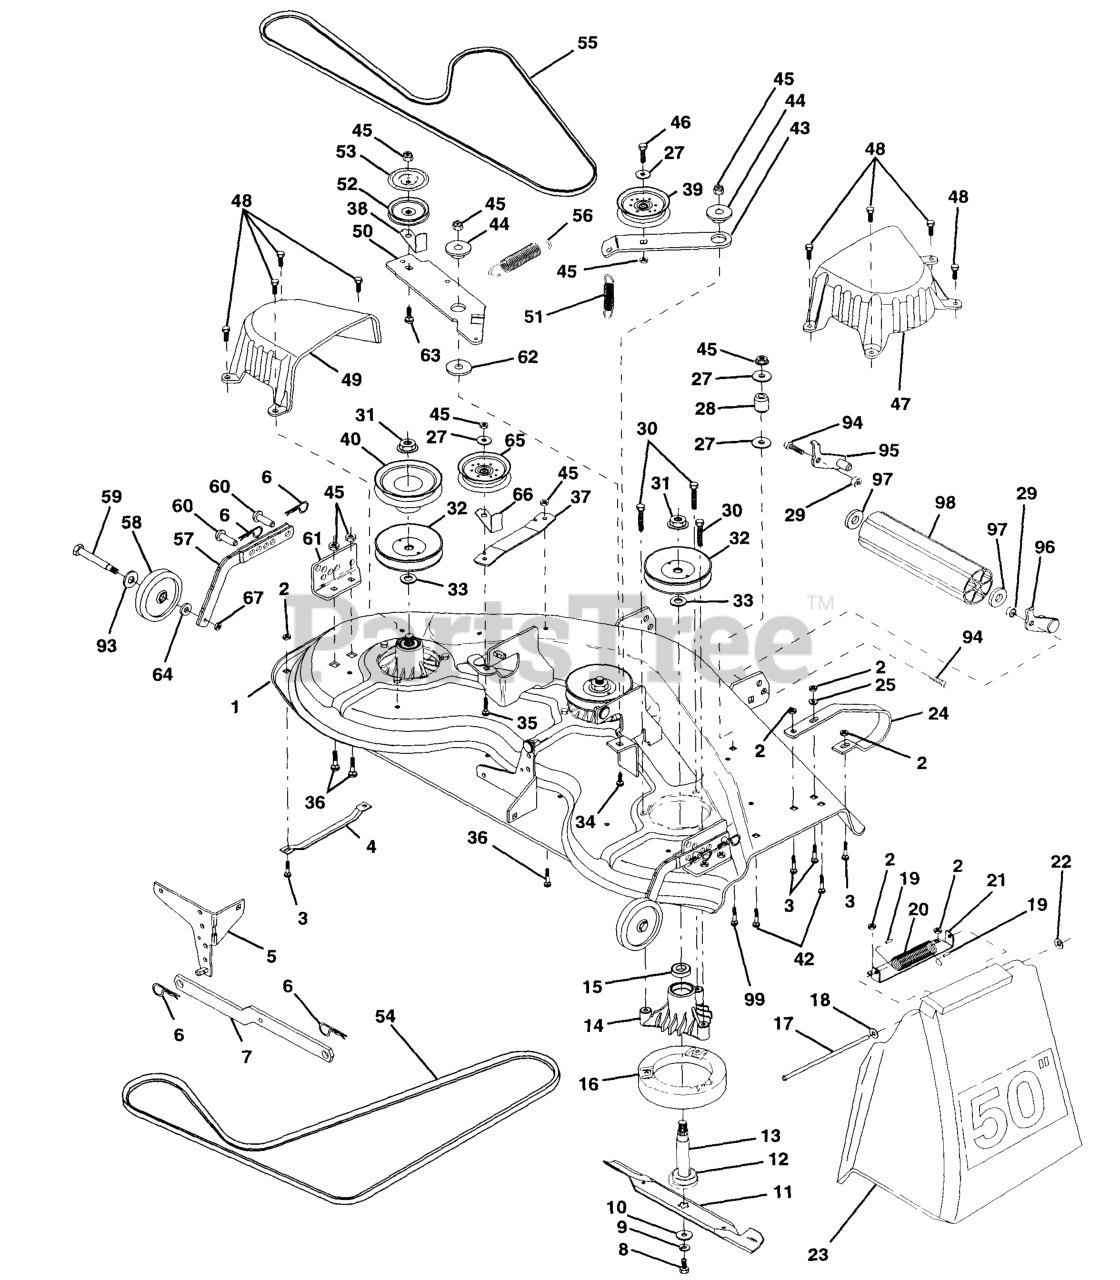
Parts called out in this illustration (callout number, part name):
1	DECK ASM MWR 50VT
2	NUT.71038.31-18.HEX.NYLOCK
3	BOLT.CARR.SQNK.5/16-18UNC.X3/4
4	RUNNER-LH M
5	BRACKET SWAY BAR
6	RETAINER-SPRNG RB
7	REAR SUSP ARM
8	BLADE BOLT
9	LOCKWASHER
10	WASHER.BLADE
11	BLADE.50".HI-LIFT
12	BEARING.BALL.#6204.(MANDREL)
13	SHAFT.ASM.W/BEARING
14	HOUSING.MANDREL.44/46" VENT
16	STRIPPER
17	ROD-HINGE T
18	Washer 11/32 x 5/8 x 16 Ga.
19	CAP-SLEEVE LT
20	SPRING TORSION
21	BRACKET, DEFLECTOR
22	NUT PUSH M
23	SHIELD.DEFLECTOR.MOWER.50"BLK.
25	WASHER M
27	WASHER
28	IDLER SPRING SPACER
29	NUT
30	SCREW
31	NUT
32	MANDREL PULLEY
33	WASHER
34	BOLT.3/8-14X1.25
35	BOLT
36	BOLT D
37	STIFFENER ARM
38	KEEPER
39	FLAT IDLER PULLEY
40	PULLEY.DRIVEN.44"
42	RP BOLT 5/16-18 X3/4 ZN/YEL GR
43	ARM.IDLER.SEC.44"
44	SPACER RETAINER
46	BOLT
47	COVER MANDRELL
48	SCREW.1/4-20X5/8
49	COVER.MANDREL.LH.44"
50	ARM.IDLER.PRIMARY
51	SPRING.SEC.44"VEN
52	PULLEY IDLER
53	SHIELD IDLER
54	V-BELT.PRMRY 46/50 VENT.BLK BK
55	BELT, V GROUND DRIVE 95 25
57	BAR.ASM.GUAGE.WHEEL
58	WHEEL.GAUGE.BLK.4.93
59	BOLT M
60	PIN.CLEVIS
61	BRACKET.GUAGE.WHEEL
62	HARDENED WASHER
63	BOLT.3/8-16X1.50
64	WASHER.5/16.FLAT.STE.STD.
65	IDLER-FLAT T
66	KEEPER
67	LOCKNUT
95	BRACKET LH (A)
96	BRACKET RH (B)
97	Washer 17/32 x 7/8 x 16 Ga.
98	NOSE ROLLER
99	BOLT
100	Washer 17/32 x 15/16 x 12 Ga.
